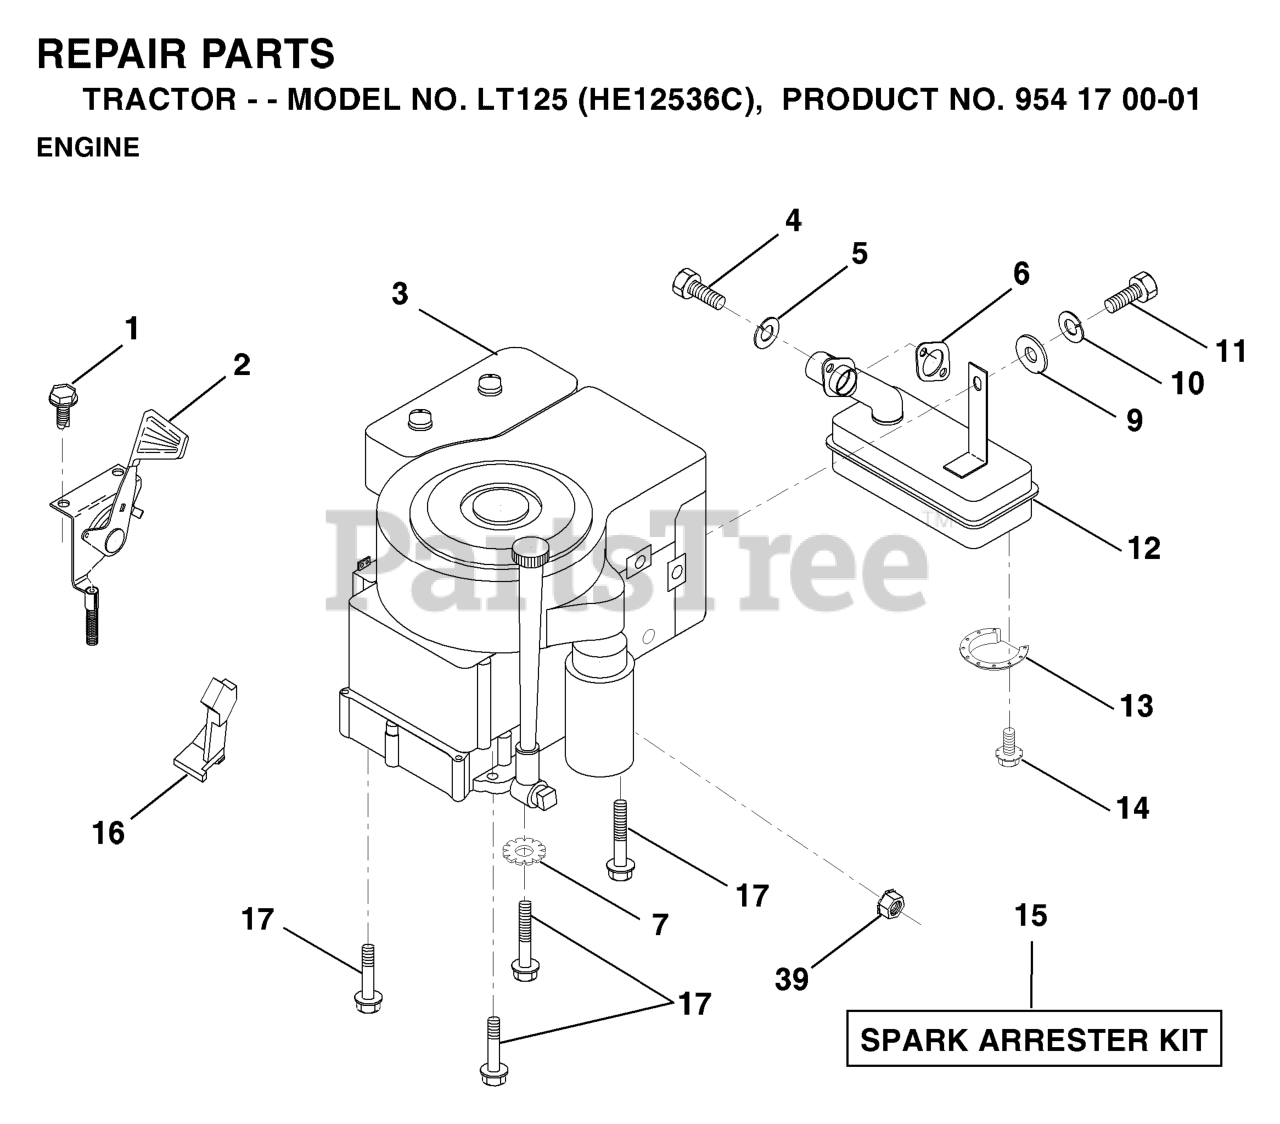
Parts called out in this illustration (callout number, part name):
2	CONTROL.TH/CH.RH.BLK.FLG.EEC
4	SCREW
5	WASHER.LOCK.HVY.HLCL.SPR.5/16
6	GASKET.ENG.1.313 ID.TIN PLATED
7	LOCKWASHER
9	WASHER
10	LOCKWASHER
12	MUFFLER.SINGLE.B&S.12HP
13	DEFL MUFFLER LTV
14	SCREW
15	KIT.SPARK ARRESTOR 794945 B&S
16	STOP THROTTLE
17	SCREW LT
39	NUT FLANGE 1/4-20 STARTER NUT
